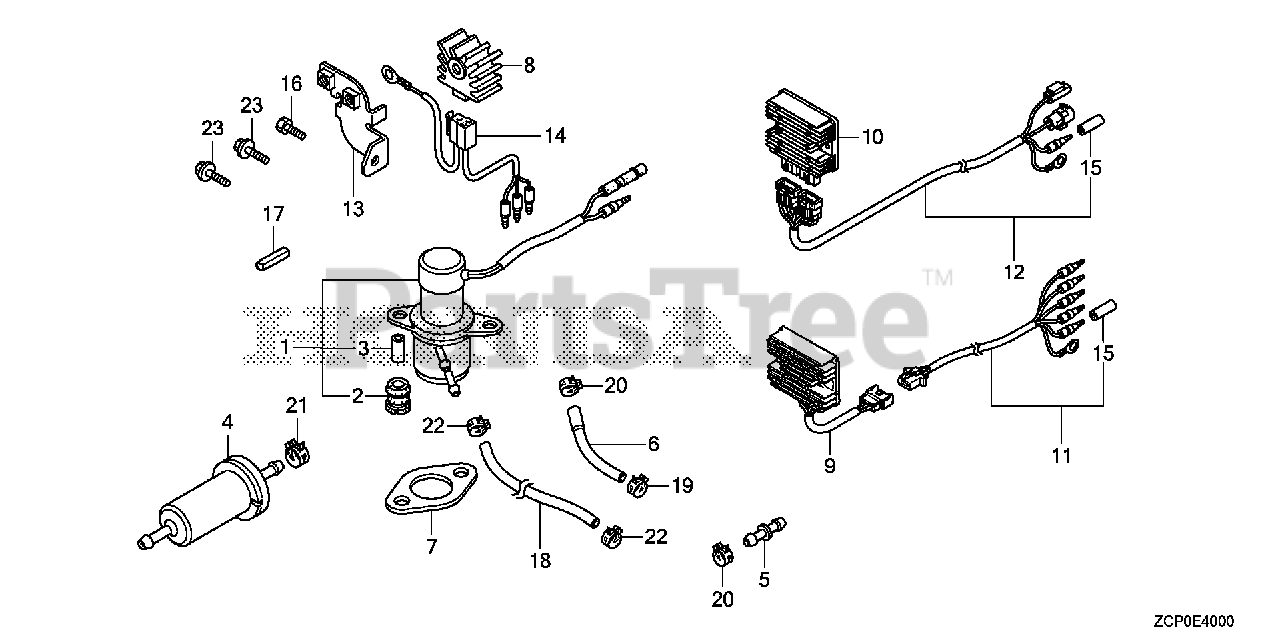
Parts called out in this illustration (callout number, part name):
7	GASKET, EX. PIPE
9	RECTIFIER ASSY., REGULATOR (20A)
11	SUB-WIRE HARNESS ASSY.
15	PLUG, CONNECTOR (OUTER)
